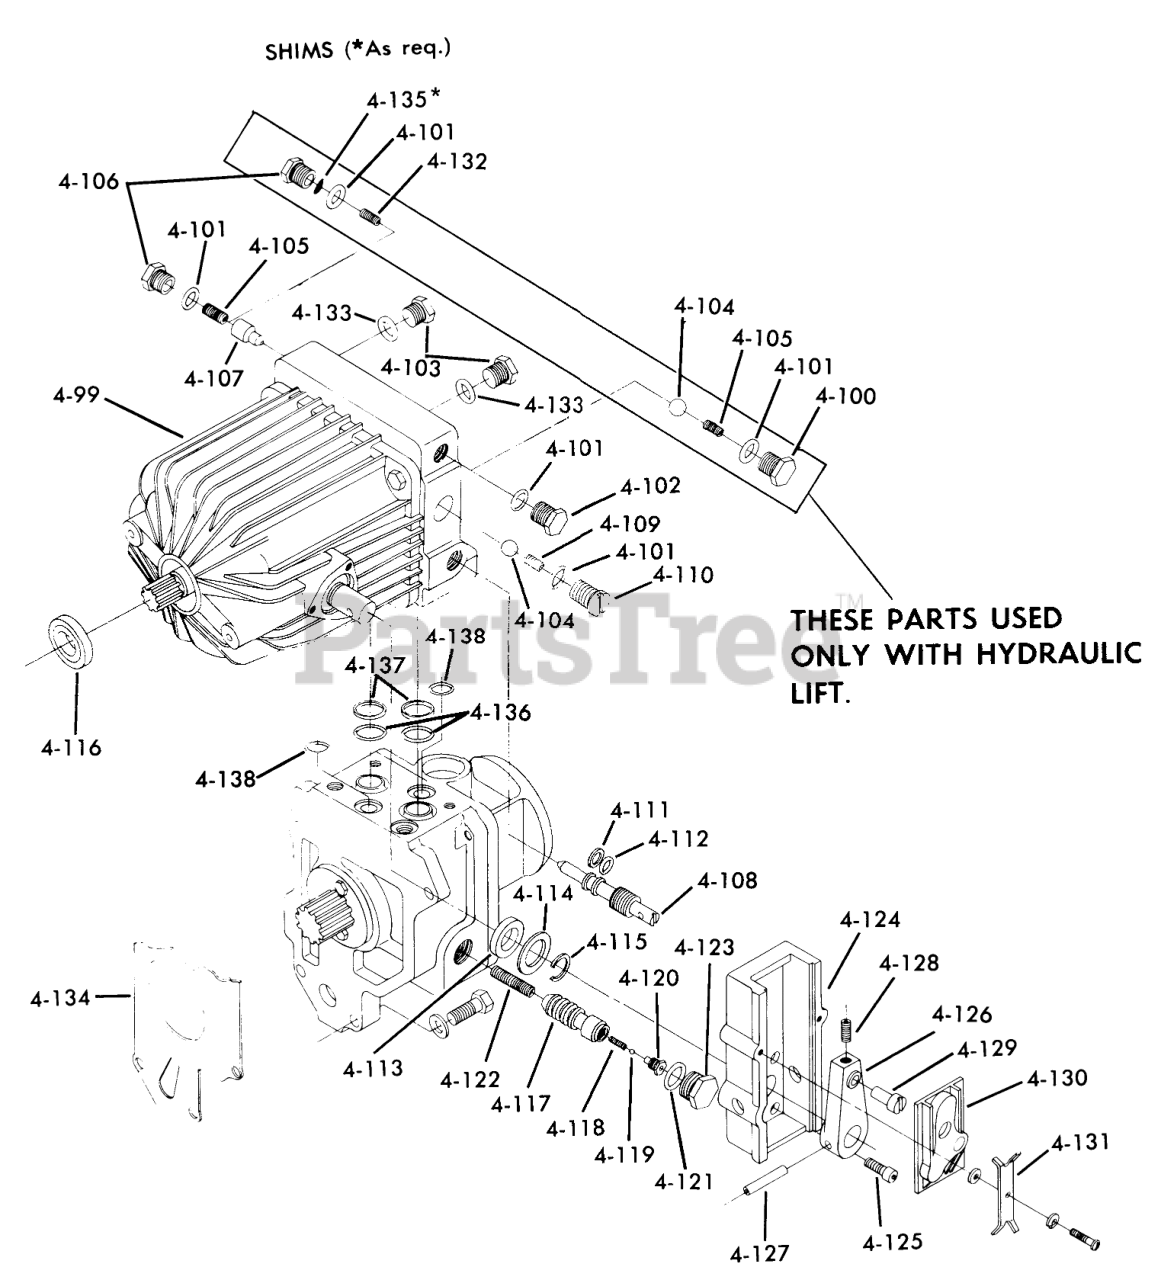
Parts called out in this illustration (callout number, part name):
4-99	Hydro Unit
4-100	Plug
4-101	O RING
4-103	Plug-Hex 9/16-18
4-105	Spring Chg. Rel. Valve
4-107	Cone
4-108	VALVE
4-109	Spring
4-110	PLUG
4-111	O-RING
4-112	Back Up Ring
4-113	SEAL
4-114	WASHER-LAMBERT
4-115	RING-LAMBERT
4-116	SEAL
4-117	Sleeve
4-118	SPRING
4-120	Valve
4-121	O-Ring
4-122	Spring
4-124	SUPPORT CAM BLOCK
4-125	SHCS 1/4-20 X 1/2
4-126	Belt Guide
4-127	PIN-ROLL 1/4 X 1 1/4
4-129	ECC CAM FOLLOWER
4-130	CAM
4-131	TENSION PLATE
4-131	SCREW
4-131	LOCKWASHER
4-131	WASHER
4-132	SPRING VALVE SUNSTR
4-133	0-Ring
4-134	GASKET
4-135	Shim Set
4-136	O RING
4-137	RING BACKUP
4-138	O RING
